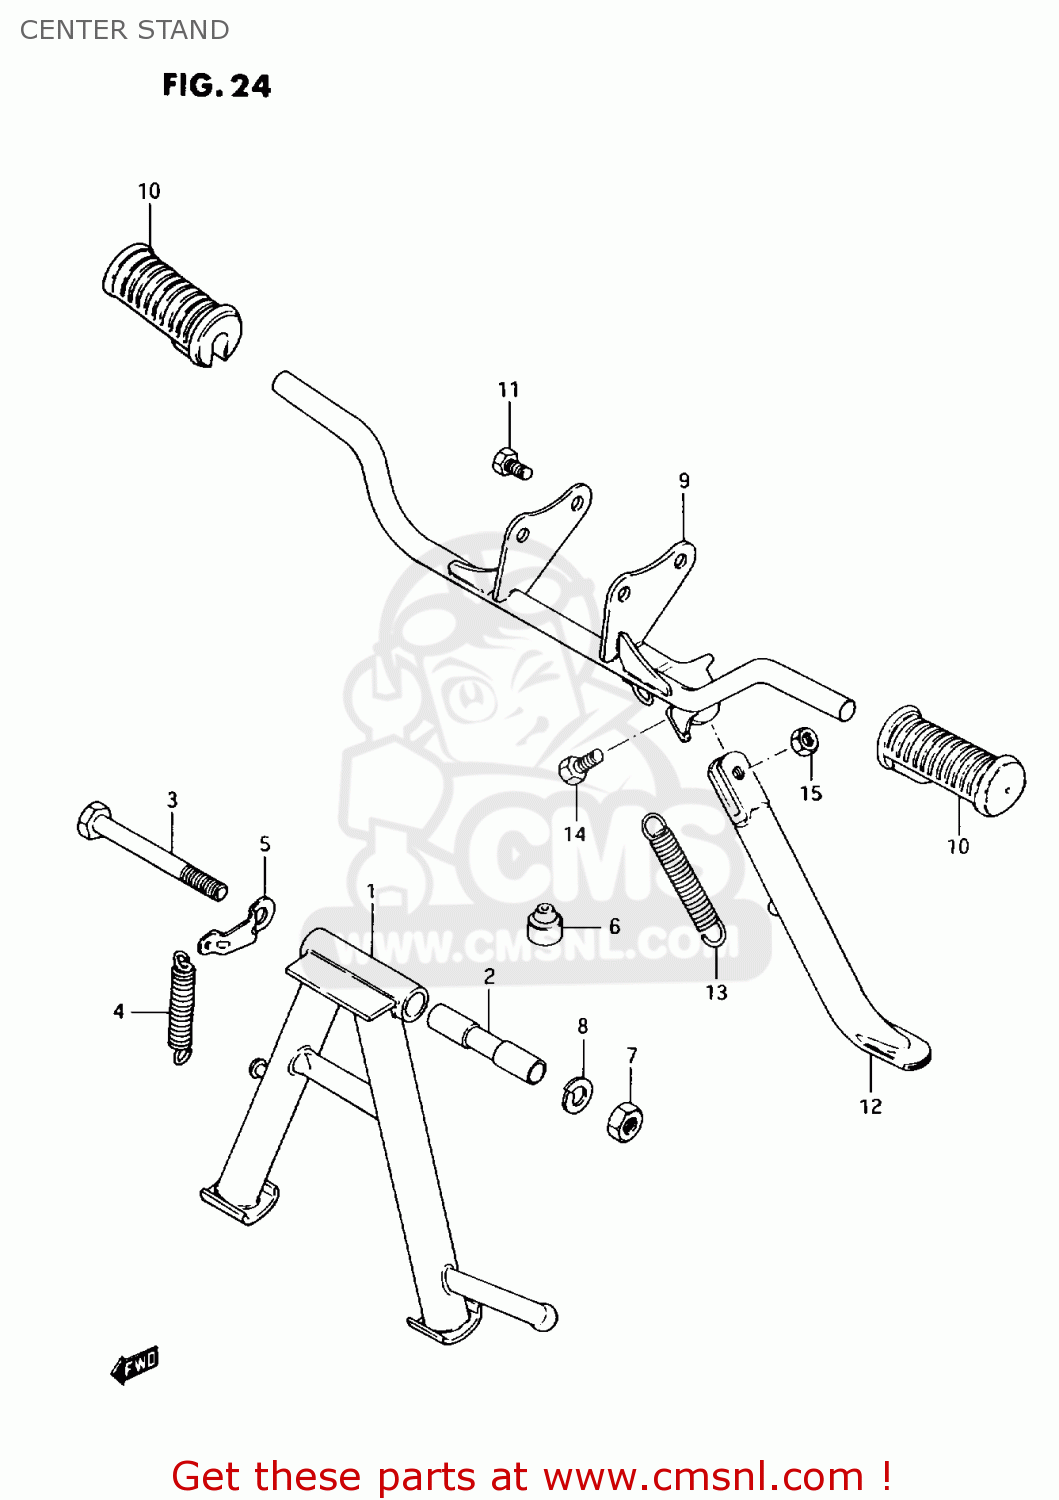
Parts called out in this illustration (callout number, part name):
1	STAND,CTR
2	SPACER
3	BOLT(10X110)
4	SPRING
5	HOOK,CTR STAND SPRING
6	CUSHION
7	NUT
8	WASHER
9	BAR,FR FOOTREST
10	RUBBER,FR FOOTREST
11	BOLT, UPPER
12	STAND,PROP
13	SPRING
14	BOLT(10X27)
15	NUT
